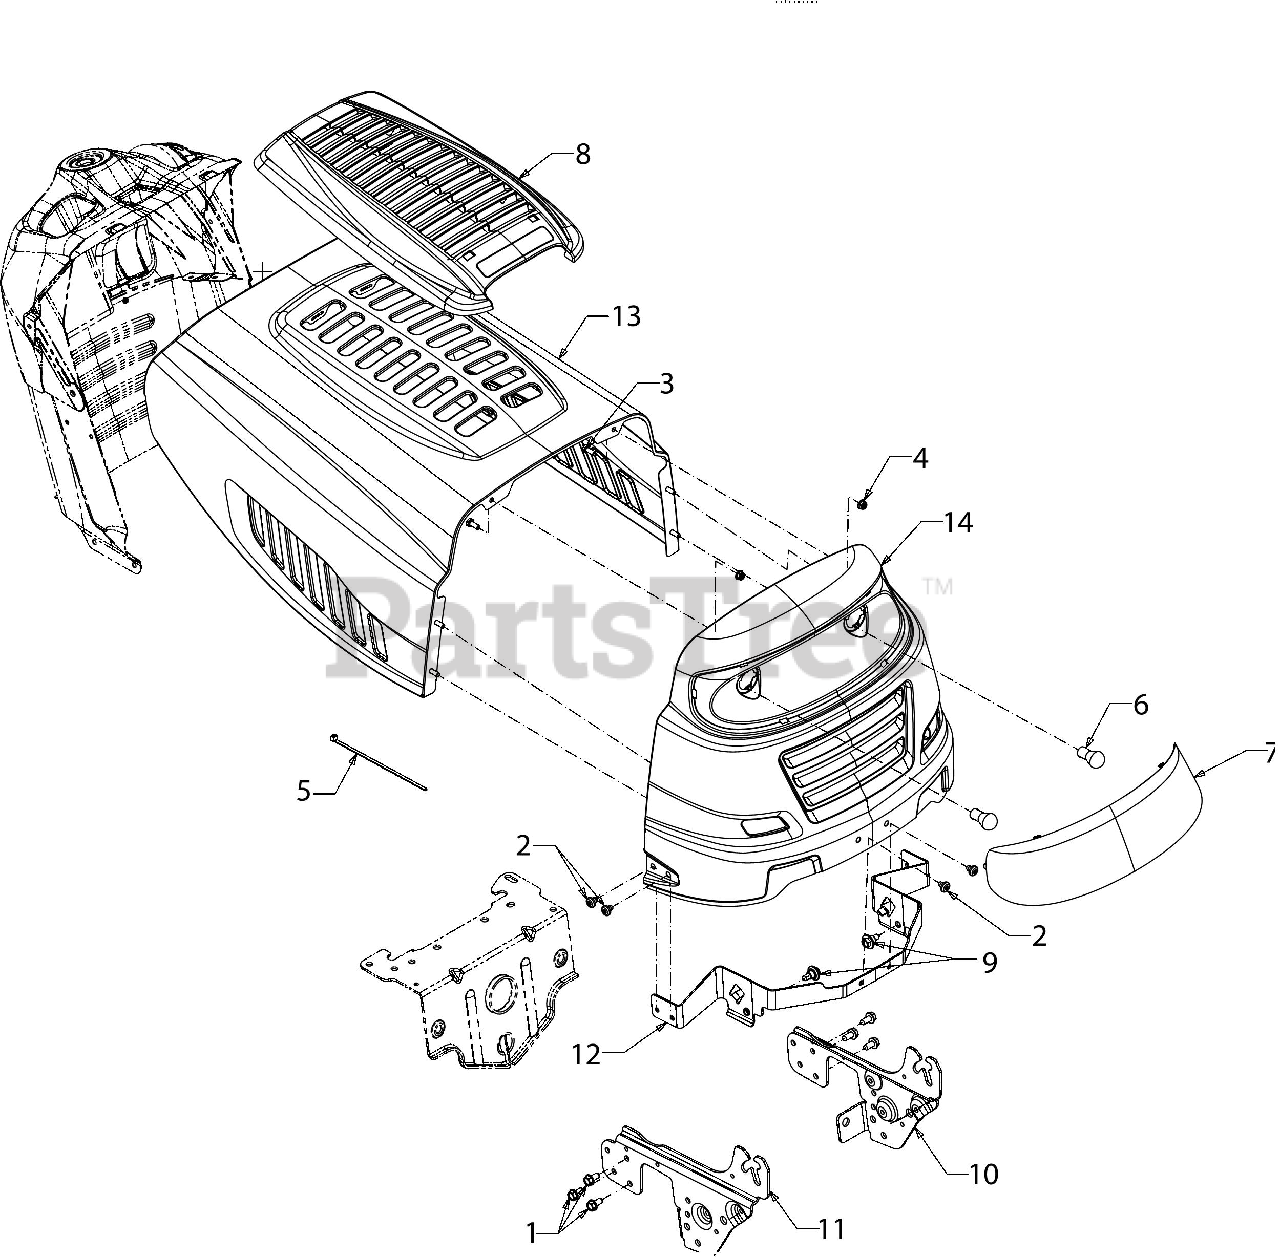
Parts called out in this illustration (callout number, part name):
1	SCREW 5/16-18 x .750
2	SCREW 5/16-18 x .375
3	SCREW 1/4-20 x .620 GR5
4	FLANGE LOCK NUT
5	7" CABLE TIE
6	MINIATUURE BULB 12V
7	GRILL LENS
8	HOOD COVER
9	SHOULDER SCREW .43X.29X5/16-18 TT
10	SUPPORT BRACKET (LH)
11	SUPPORT BRACKET (RH)
12	HOOD PIVOT BRACKET
13	HOOD-5-STYLE
14	GRILLE-1 STYLE
